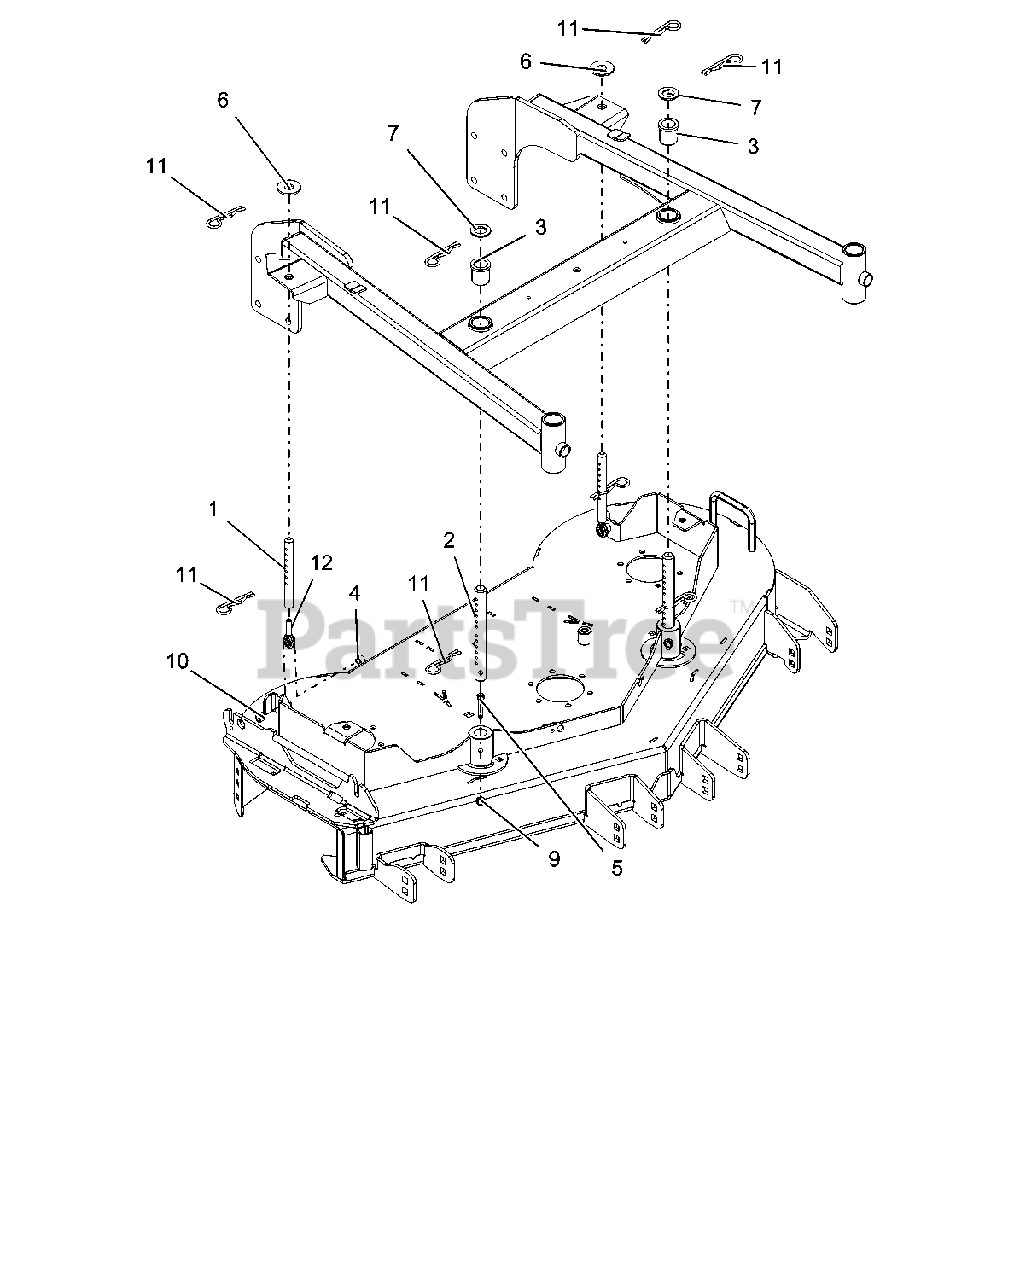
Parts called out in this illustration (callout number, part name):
1	ROD, REAR HOC
2	PIN, FRONT HOC
3	BSHG-FLG 1.00X1.25X1.5X1.5
4	BSHG, SLV REV
5	BLT-HEX .31-18X2.50 GR8 YWZC
6	WSHR-FL-STL.688X1.75X.134 YWZ
7	WSHR-FL-STL .875X1.500X.1196YZ
9	@NUT-SPNLK-FLG .312-18 YWZC
10	NUT-LK-NYL .38-16 YWZC
11	PIN-HAIR-INT .17X.68X3.50 YWZC
12	ROD, END 3/8 RH REV
